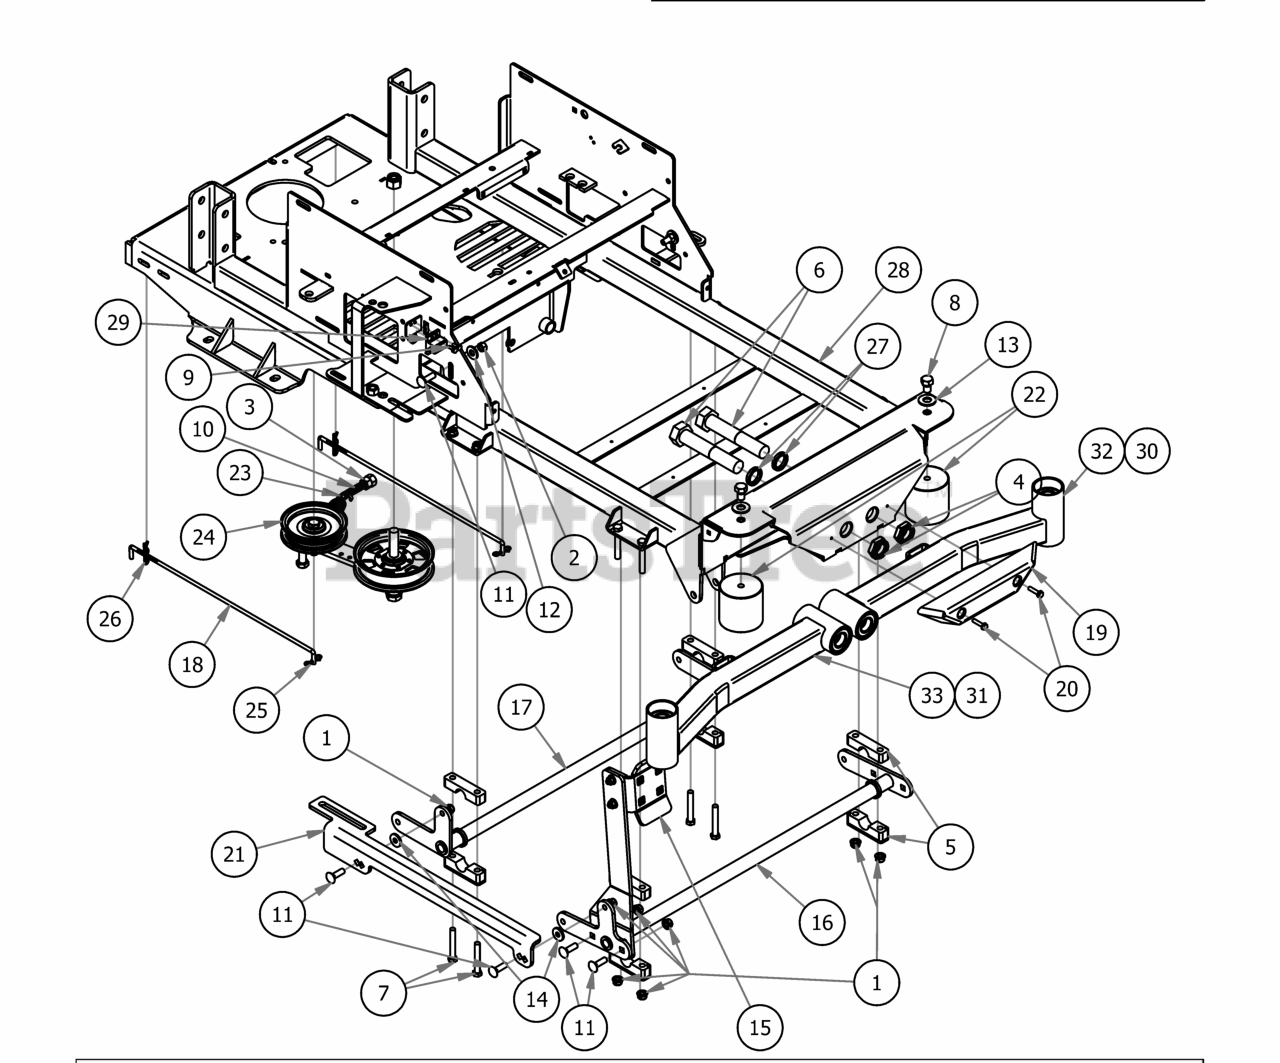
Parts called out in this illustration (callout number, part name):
1	3/8" Nylock Flange Nut
2	3/8" Hex Nut
3	1/2" Hex Nut
4	1" Fine Thread 1/2 Nylock Nut
5	Pillow Block Kit
6	1-14 x 5.5 Hex Bolt Grade 8 Zinc Yellow
7	3/8-16 x 2 1/2" Hex Bolt
8	1/2" x 3/4" Hex Bolt
9	12-24x 1/2 HWH Bolt
10	All Thread-Pump Idler Tensioner
11	3/8" x 1 1/4" Carriage Bolt
12	3/8" Flat Washer
13	1/2" Washer (Grade 8)
14	.360 ID Plastic Washer
15	Foot Pedal Assembly
16	Actuator Bar Front- 2017 MZ/ZT
17	Actuator Bar Rear- 2017 MZ/ZT
18	Neutral Rod
19	Front Bumper
20	1/4 x 1 Hex Head Tek screw
21	2017 MZ/ZT Actuator Linkage
22	Vibration Mount- Red Dot
23	Deck Idler Spring
24	Maverick Pump Idler
26	Neutral Rod Clip
27	Spacer, 1x1.375x.25
28	2018 Maverick Frame
29	Safety Switch
30	2018 Maverick Suspension Arm Assembly-Left Short (48" Deck Only)
31	2018 Maverick Suspension Arm Assembly-Right Short (48" Deck Only)
32	2018 Maverick Suspension Arm Assembly-Long, Left
33	2018 Maverick Suspension Arm Assembly-Long, Right
